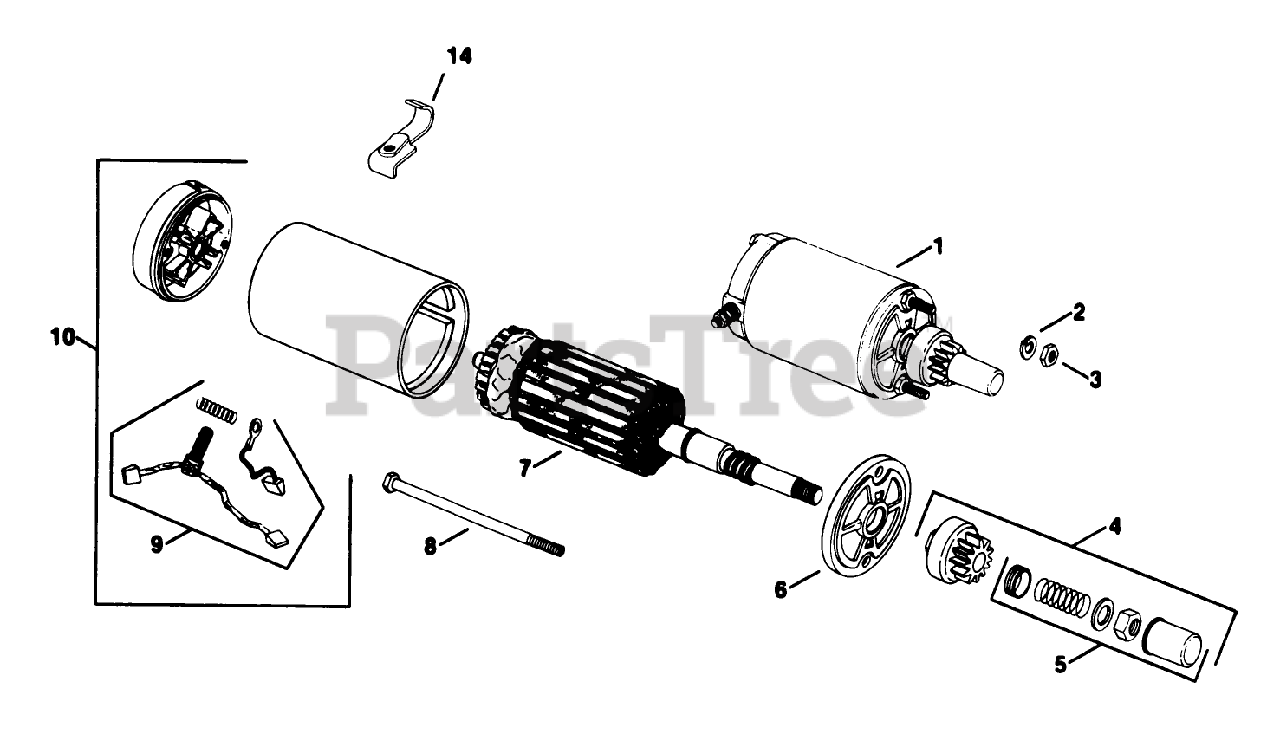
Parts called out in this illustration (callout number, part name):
1	Starter Assy. (Incl. Ref. #4-10)
2	Washer
4	Kit-Drive
5	Kit-Drive Parts
6	Cap-Drive End
7	Armature
9	Kit-Brush
10	Kit-Commutator End Cap
14	Bracket-Mounting
